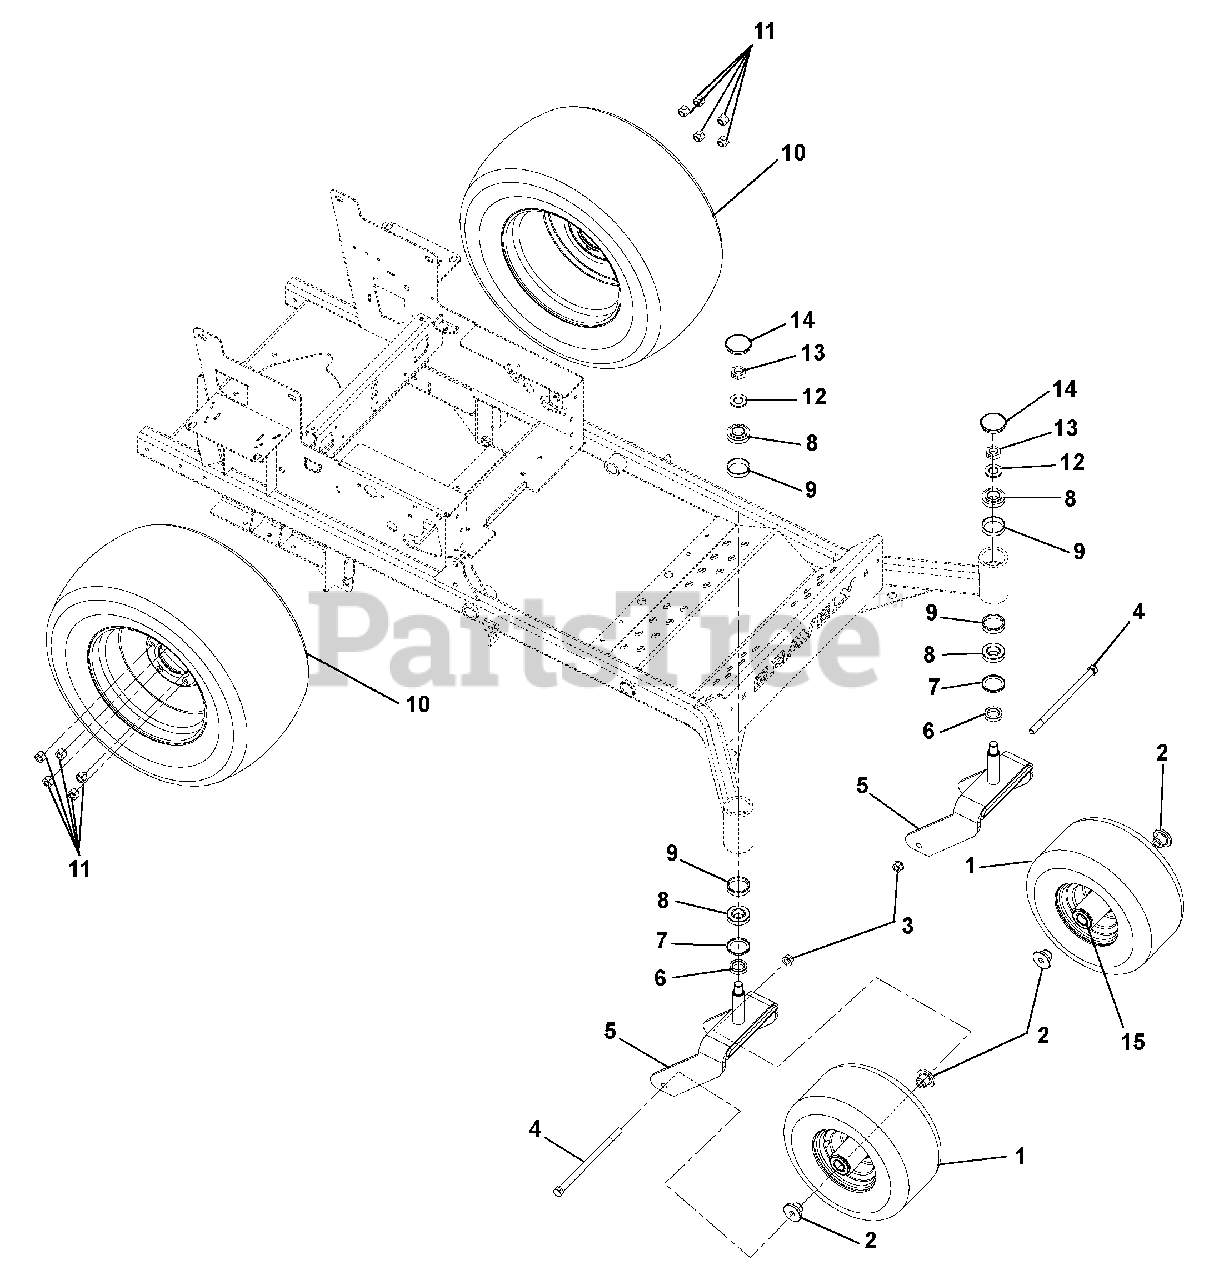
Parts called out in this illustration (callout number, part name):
1	TIRE/WHEEL ASM, 13X6.50-6
2	SPACER, FRONT WHEEL
3	NUT-LK-NYL-FLG .50-13 YWZC
4	BLT-HEX .50-13X9.00 GR5 YWZC
5	FORK - BLACK
6	SPACER 1.005X1.5075X.375
7	BEARING SEAL 1.5 X 2 X .18
8	BRG-CONE 1.0X.58
9	BRG-CUP1.980X.420
10	TIRE/WHEEL ASSY, 23X10.00-12
11	WHEEL NUT .500-20 YZ
12	WSHR-FL-STL.812X1.50X.135YWZC
13	NUT-JAM CTRLK .75-16 YWZC
14	CAP, DUST
15	BRG, 25MM ID X 52MM OD X 15MM
